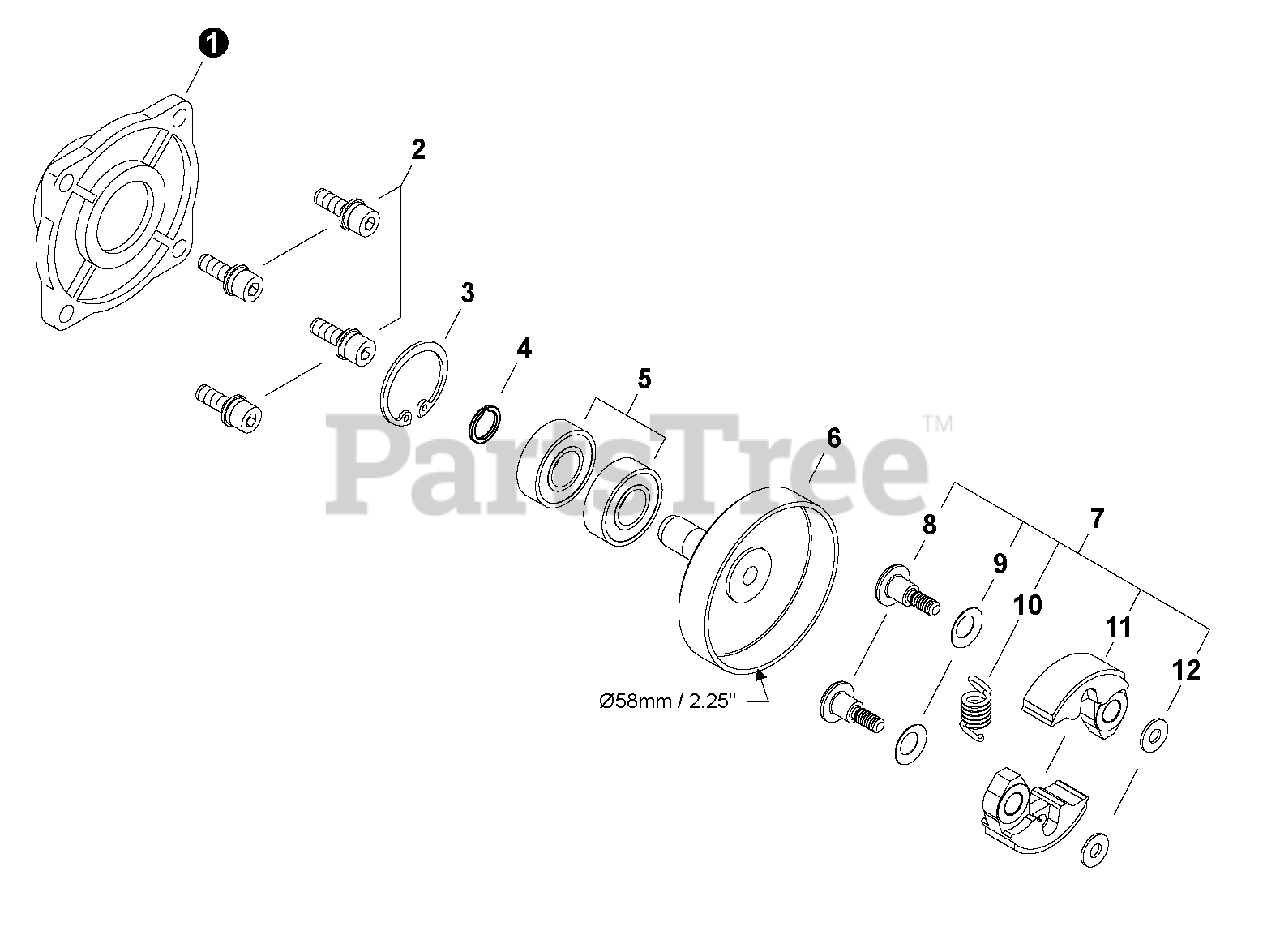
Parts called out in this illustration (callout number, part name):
1	CASE, CLUTCH
2	BOLT M5×16
3	RING, SNAP Ø28
4	RING, SNAP Ø12
5	BEARING, BALL 6001 DDU C3
6	DRUM, CLUTCH
7	CLUTCH ASSY
8	BOLT, CLUTCH
9	WASHER, SPRING
10	SPRING, CLUTCH
11	SHOE, CLUTCH
12	WASHER 6 MM
